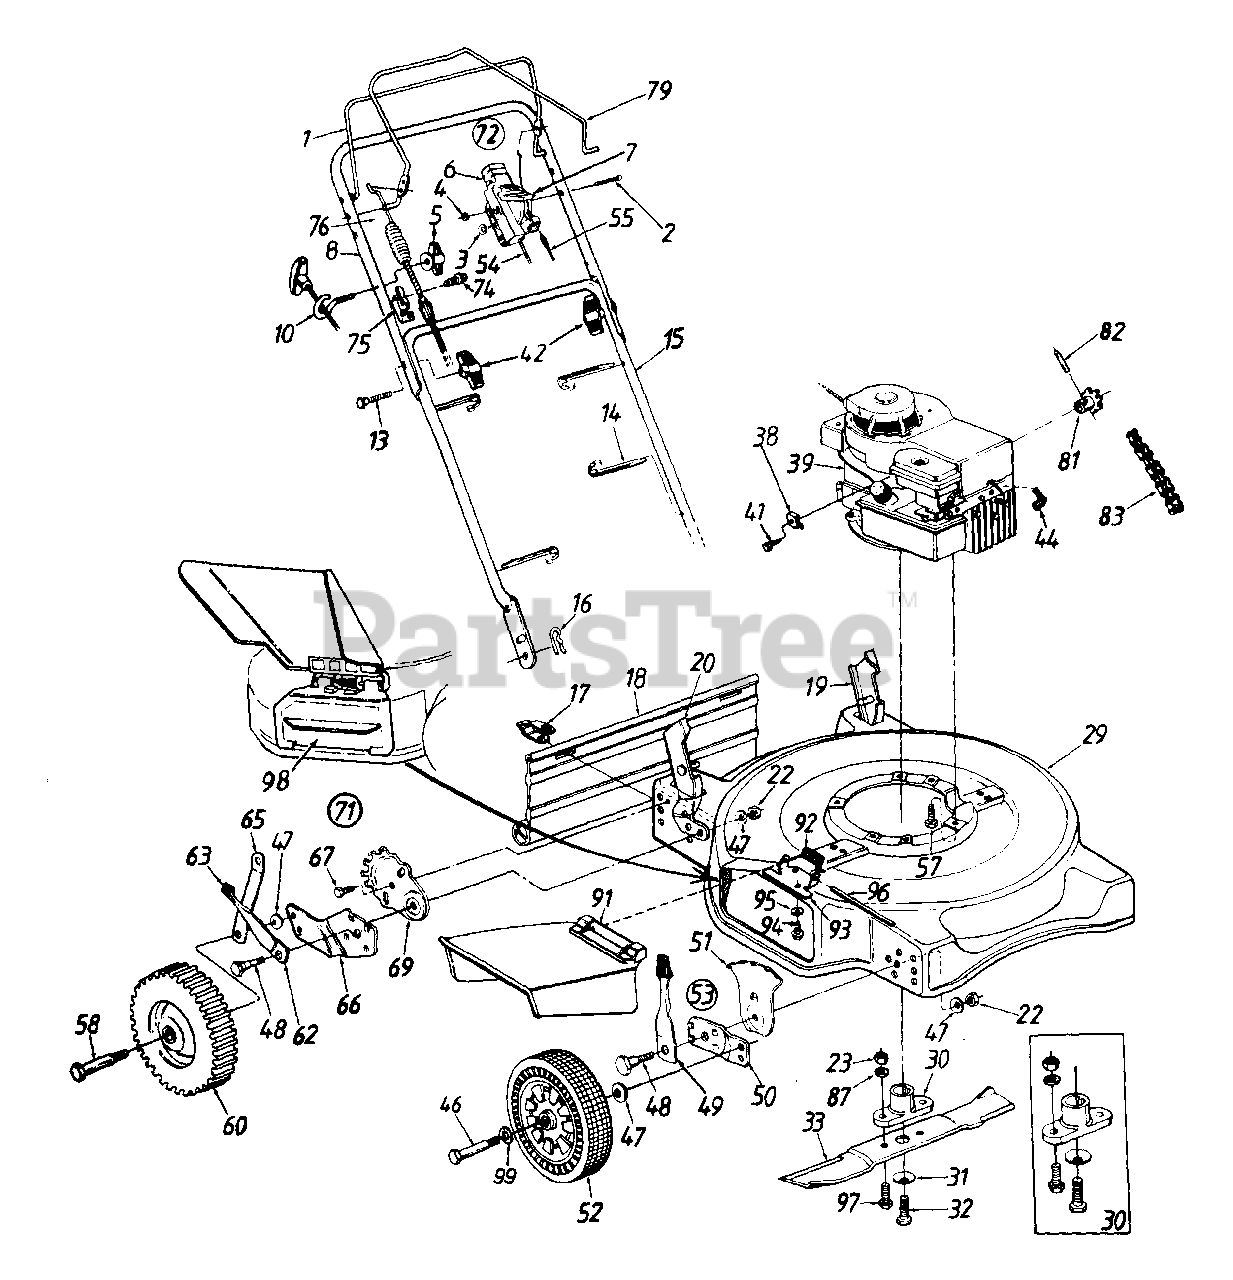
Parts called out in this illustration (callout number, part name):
2	Oval C-Sunk Mach. Scr.
3	Spr. Wash..66" I.D.
4	Hex L-Nut 1/4-20 Thd.
5	Wing Nut 1/4-20 Thd.
6	Throttle Body
7	Throttle Lever
13	Curved Hd. Bolt 5/16-18 x 2" Lg.
14	Cable Tie
16	Hairpin Cotter
17	Hinge Clip
18	Rear Flap
23	Hex Nut 3/8-24 Thd.
29	22" Deck Ass'y.
30	Blade Adapter Kit
31	Bell-Wash..39" I.D.
32	Hex Bolt 3/8-24 x 1.5" Lg.
33	22" Blade
38	Cable Clamp (B&S)
39	Engine
41	Hex Wash. Hd. Scr. #10-32 x .62" Lg. (B&S)
42	Hand Knob
44	Spark Plug Boot
46	Front Axle Bolt
47	Bell-Wash..400" I.D. x .88"
48	Shld. Bolt .50" Dia. x .357"
49	Spring Lever Ass'y. w/Knob
51	Height Adj. Plate
52	Front Wheel Ass'y. Comp.
53	Height Adj. Ass'y. Comp.- R.H.
54	Throttle Control Wire 51" Lg. (B&S)
55	Control Cable - 39" (B&S)
57	Hex L-Wash. Hd. Scr. 3/8-16 x 1.0" Lg.
58	Rear Axle Bolt
60	Rear Wheel Ass'y. Comp.
62	Spring Lever
63	Spring Lever Knob
67	Hex AB-Tap 1/4-.62" Lg.
69	Index Plate
71	Rear Height Adj. Ass'y.- R.N.
72	Throttle Box Comp.
74	Hex Wash. AB-Tap Scr. 5/16 x .75" Lg.
75	Cable Brkt.
76	Clutch Cable
82	Spring Pin Spir. 3/16" Dia. x 1" Lg.
83	#48 Chain 1/2" Pitch 50 Links (Endless)
87	L-Wash. 3/8" I.D.
91	Chute Deflector Ass'y.
92	Torsion Spring
93	Adapter Plate
94	Hex Self-Tap Scr. 1/4-20 x .5" Lg.
95	Bell-Wash. 1/4" I.D.
96	Hinge Pin
97	Hex Bolt 3/8-24 x 1" Lg.
98	Mulching Plug
99	Wave Washer .51" I.D.
